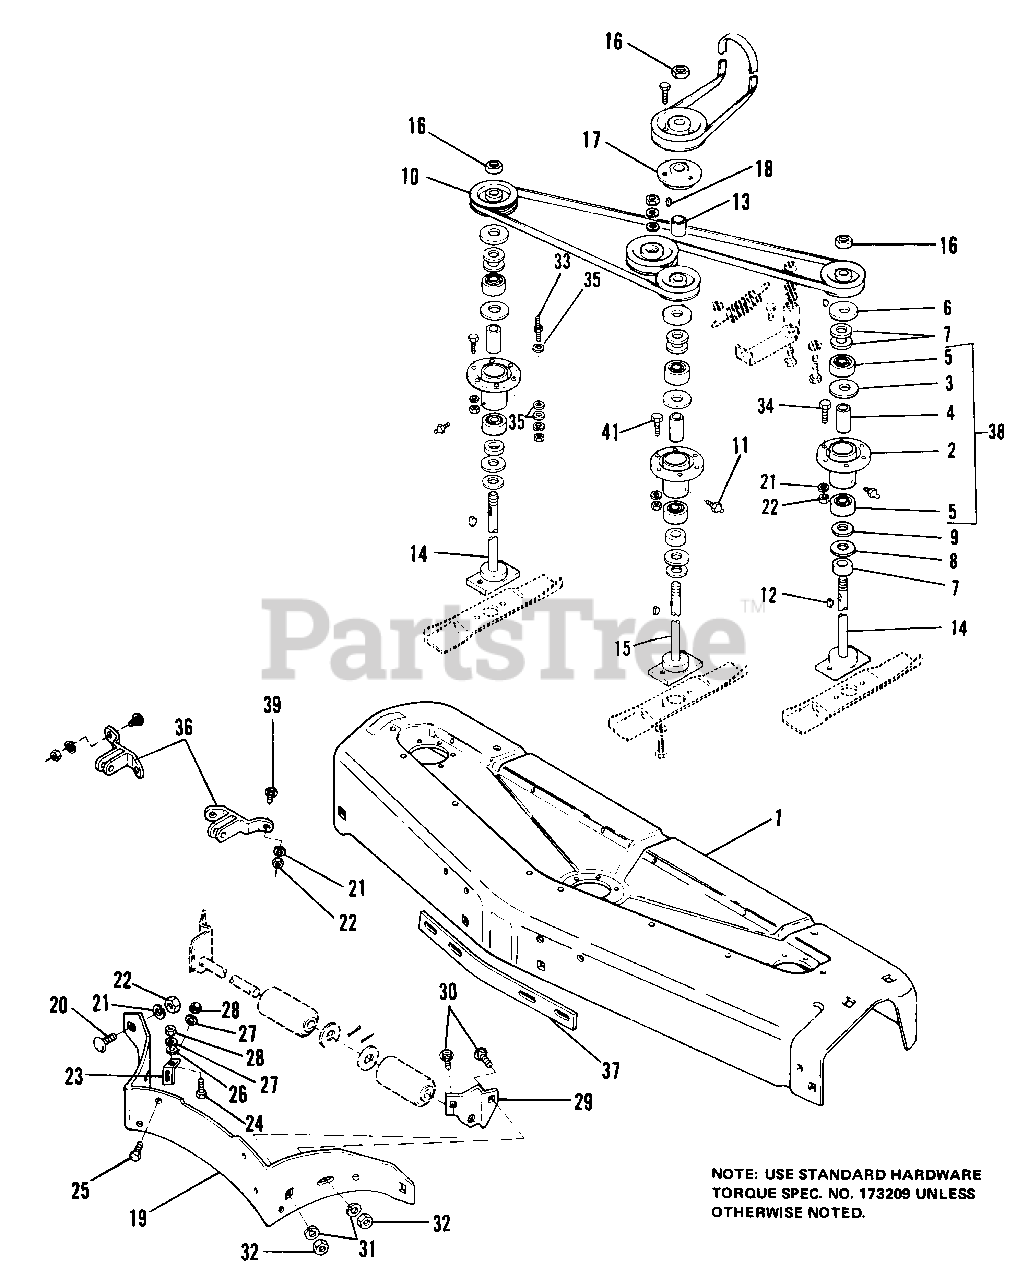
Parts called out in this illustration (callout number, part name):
1	HOUSING, 48"
2	TUBE SUB-ASSY
3	RING, Backing
5	BEARING, Ball
11	FITTING, Lube, Drive Type, 1/4
12	KEY, Woodruff, No. 61, 3/16 x 5/8
15	ARBOR ASSY, Drive
16	NUT, Hex Lock, 3/4-16
17	HUB, Pulley
20	BOLT, Rd.Hd., 3/8-16 x 3/4
21	LOCKWASHER, Spring, 3/8
22	NUT, Hex, 1/4-20
23	CLIP, Baffle
24	SCREW, Thread Cutting, 1/4-20 x 7/8
25	CAPSCREW, Hex Hd., 1/4-20 x 5/8
26	WASHER, Plain, 1/4
27	LOCKWASHER, Spring, 1/4
28	NUT, Hex, 1/4-20
29	BRACKET, Roller,L.H.
30	BOLT, Rd. Hd., 5/16-18 x 3/4
31	LOCKWASHER, Spring, 5/16
32	NUT, Hex, 5/16-18
34	CAPSCREW, Hex Hd., 3/8-16 x 3/4
35	WASHER, Plain, 5/16
36	BRACKET ASSY, Front
37	BAR, Reif.
38	BEARING & TUBE SUB-ASSY
39	BOLT, Rd. Hd., 3/8-16 x 1
40	DECAL, Caution
41	SCREW, Special
42	ARBOR KIT, Outside
43	ARBOR KIT, Center
